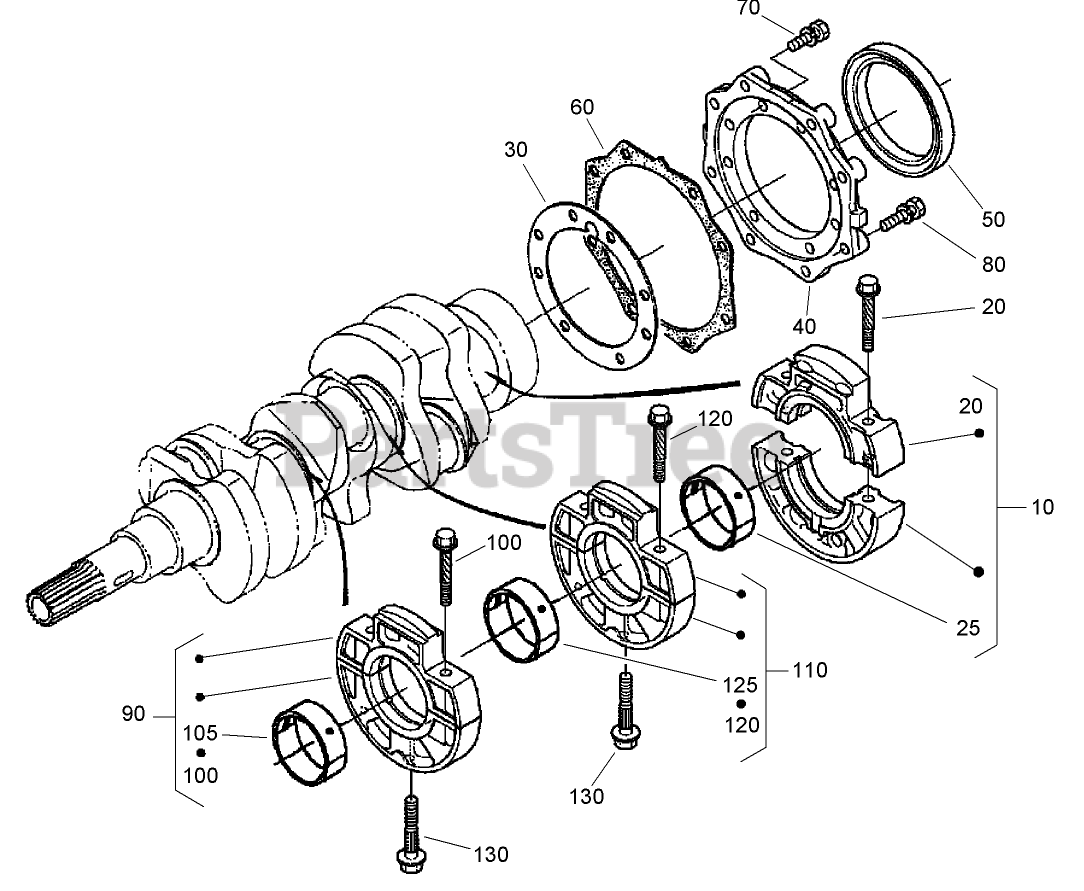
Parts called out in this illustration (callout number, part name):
10	WHEEL CASE BEARING ASM
20	BOLT-CASE, BEARING
25	CRANKSHAFT METAL ASM (STD)
25	CRANKSHAFT METAL ASM (-0.20MM)
25	CRANKSHAFT METAL ASM (-0.40MM)
30	GASKET-CASE, BEARING
40	COVER-CASE, BEARING
50	SEAL-OIL
60	GASKET-COVER, CASE
90	MAIN CASE BEARING ASM
100	BOLT-CASE, BEARING
105	CRANKSHAFT METAL ASM (STD)
105	CRANKSHAFT METAL ASM (-0.20MM)
105	CRANKSHAFT METAL ASM (-0.40mm)
110	MAIN CASE BEARING ASM
120	BOLT-CASE, BEARING
125	CRANKSHAFT METAL ASM (STD)
125	CRANKSHAFT METAL ASM (-0.20MM)
125	CRANKSHAFT METAL ASM (-0.40mm)
130	BOLT-CASE, BEARING
